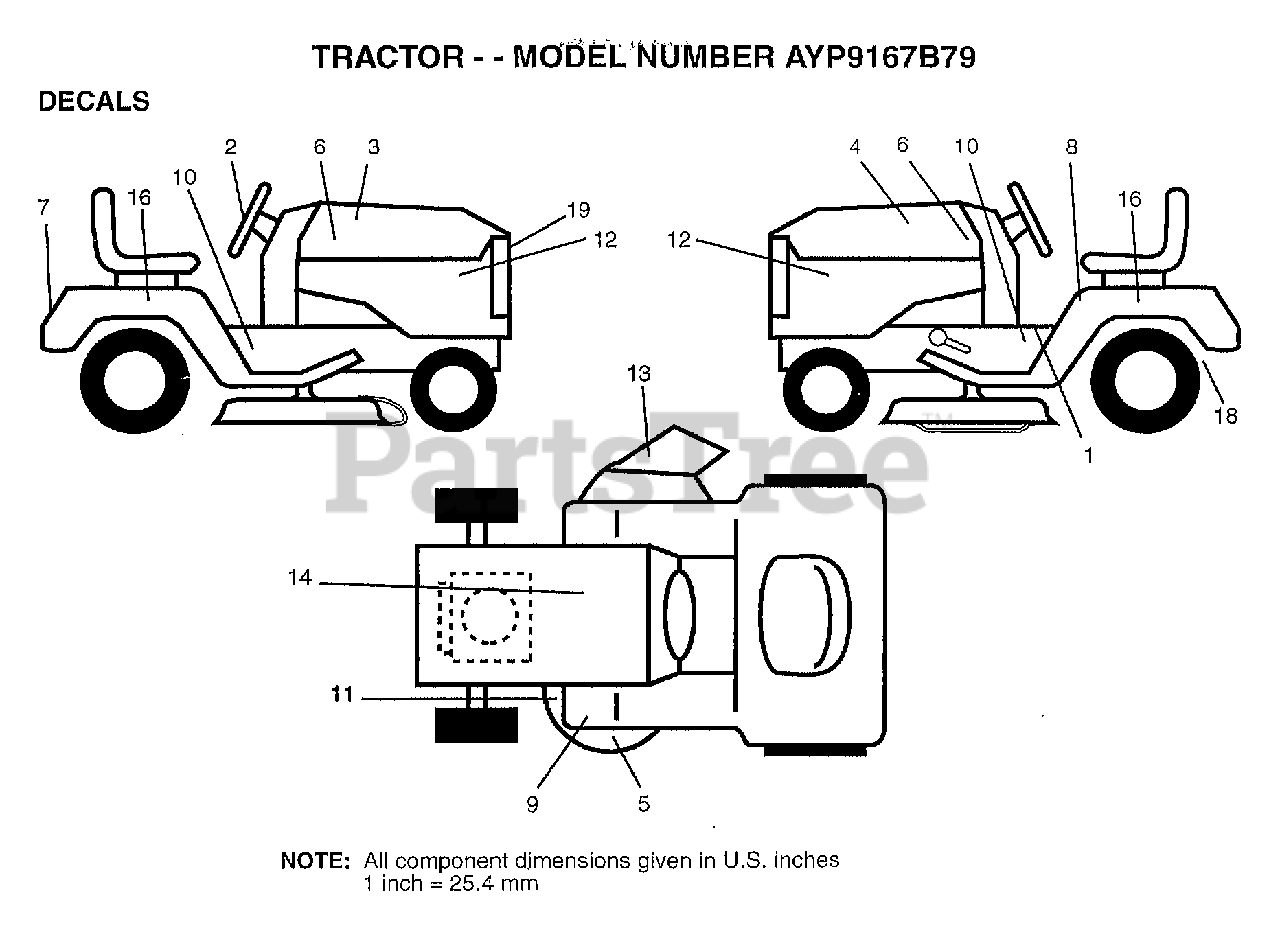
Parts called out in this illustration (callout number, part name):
1	"DECAL INST,SADDLE"
2	DECAL STEER WHL
3	DECAL HOOD RH
4	DECAL HOOD LH
5	DECAL DECK WIZ +
6	NAMEPLATE.HD.WIZA
8	"DECAL DANGER,FEND"
10	"DECAL.CHASSIS.42"""
11	DECAL
12	"DECAL PANEL,SIDE"
13	DECAL DECK MULCH
14	DECAL.BATRY.3-3908
16	DECAL.FENDER.WIZ
18	DECAL DRAWBAR LH
19	DECAL.LENS.WIZARD
